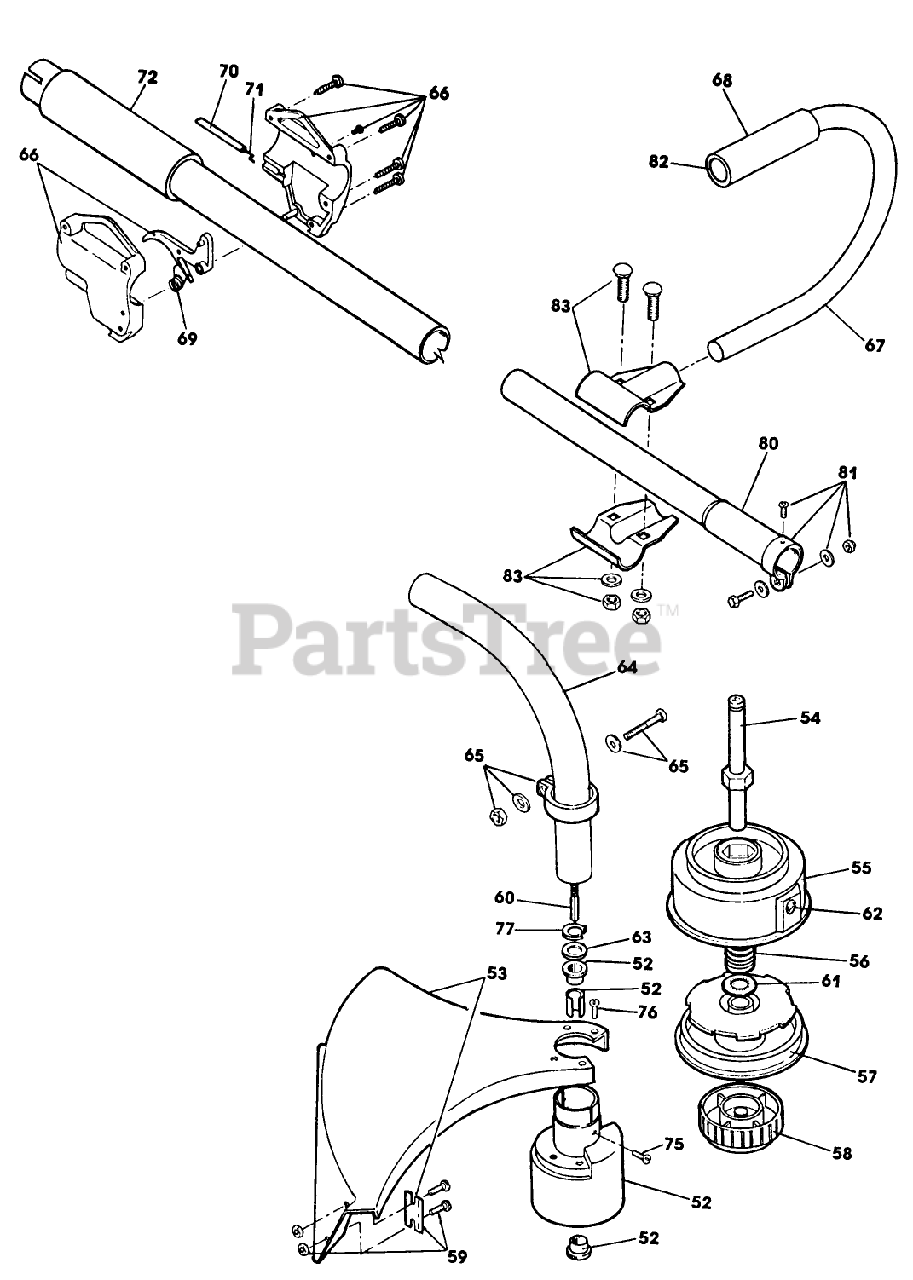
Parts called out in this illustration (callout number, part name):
52	BUSHING HSG ASM
57	REEL - INNER
59	BLADE ASM
61	RETAINER WASHER
66	THROTTLE TRIGGER ASM
68	HANDLE NITRILE GRIP
69	THROTTLE TRIGGER SPRING
70	THROTTLE CABLE HSG
71	THROTTLE CABLE WIRE
75	ANTI-ROTATION SCREW
76	GUARD MOUNTING SCREW
77	RETAINING RING
82	TUBE CLOSURE
